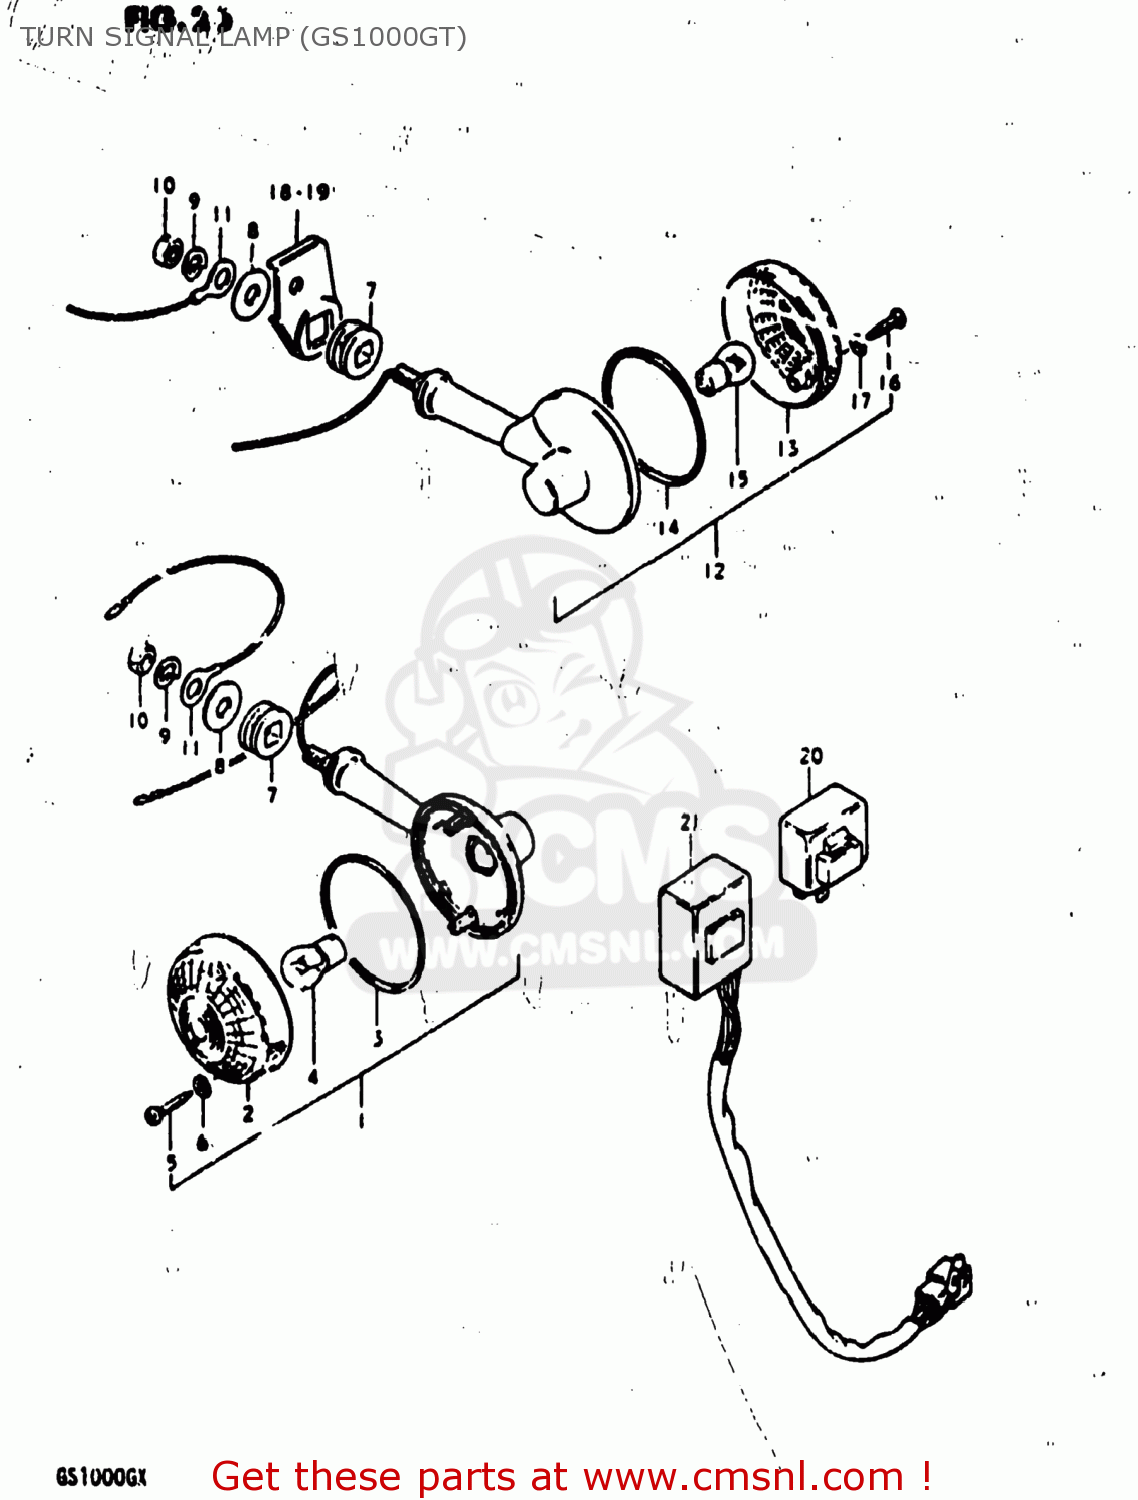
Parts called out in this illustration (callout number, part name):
1	LAMP ASSEMBLY,FRONT TURN SIGNAL
2	LENS
3	GASKET (NAS)
4	BULB(12V23W,STANLEY,A4577A)
5	BOLT
6	GASKET (NAS)
7	CUSHION
8	WASHER
9	LOCK WASHER
10	NUT
11	LEAD WIRE,EARTH
12	LAMP ASSEMBLY,FRONT TURN SIGNAL
13	LENS
14	GASKET (NAS)
15	BULB(12V23W,STANLEY,A4577A)
16	BOLT
17	GASKET (NAS)
18	BRACKET,RR TURNSIGNAL LAMP,R
19	BRACKET,RR TURNSIGNAL LAMP,L
20	RELAY ASSY,TURNSIGNAL
21	UNIT,TURN SIGNAL CONTROL
